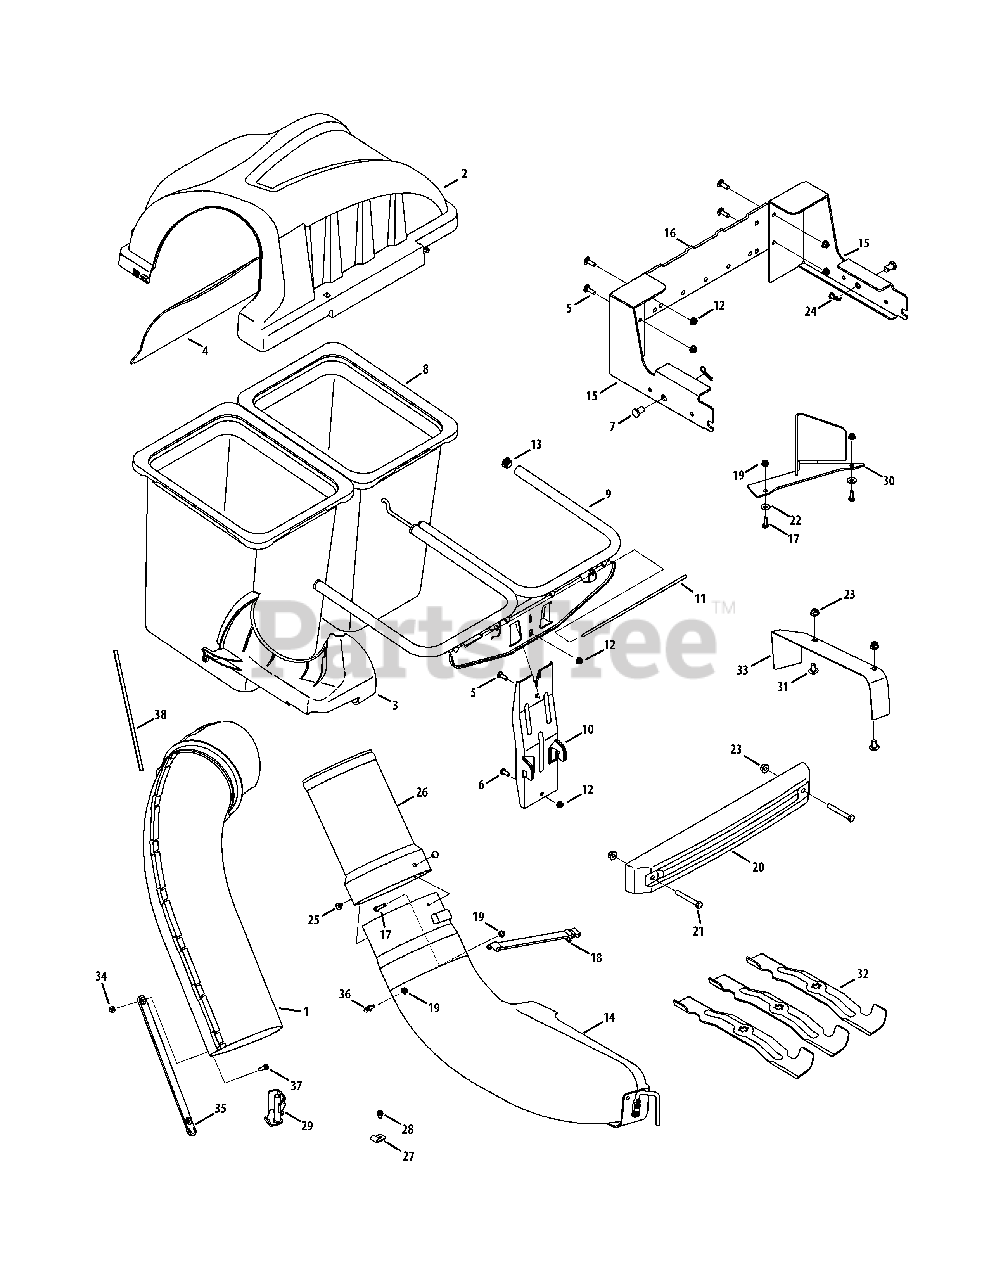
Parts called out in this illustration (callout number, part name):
1	Upper Chute Assembly
2	Twin Bagger Cover Assembly
3	Upper Chute Support
4	Bagger Cover Screen
5	Carriage Screw, 5/16-18 x 1.00"
6	Hex Head Screw, 5/16-18 x .75"
7	Clevis Pin, .50" Dia.
8	Grass-bag Assembly
9	Twin Bag Support Assembly
10	Vertical Support Bracket
11	Cover Hinge Pin
12	Flange Lock Nut, 5/16-18
13	End Plug
14	Discharge Chute Elbow
15	RZT Hitch Bracket Kit (RH & LH)
16	Universal Cross Bracket
17	Hex Head Screw, 1/4 - 20 x .75
18	Chute Strap
19	Flange Lock Nut, 1/4 - 20
20	Bagger Weight
21	Hex Head Screw, 3/8 - 16 x 2.75
22	Belleville Washer
23	Flange Lock Nut, 3/8 - 16
24	Cotter Pin, .080 x 1.5625 Internal
25	Ratchet Clip, .250
26	Bagger Chute Adapter, 8 x 13.5
27	Retainer Hook Bracket
28	Self-Tap Screw, 1/4-20 x .500
29	Chute Stop Bracket
30	Deck Baffle, 50"
31	Carriage Bolt, 3/8-16 x 1.00
32	Bagging Blade, 17.90 Lg. Star
33	Chute Discharge Plate
34	Flange Lock Nut, 1/4-20
35	Chute Strap
36	Grass-catcher Pin
37	Machine Screw, 1/4-20
38	Adhesive Strip
